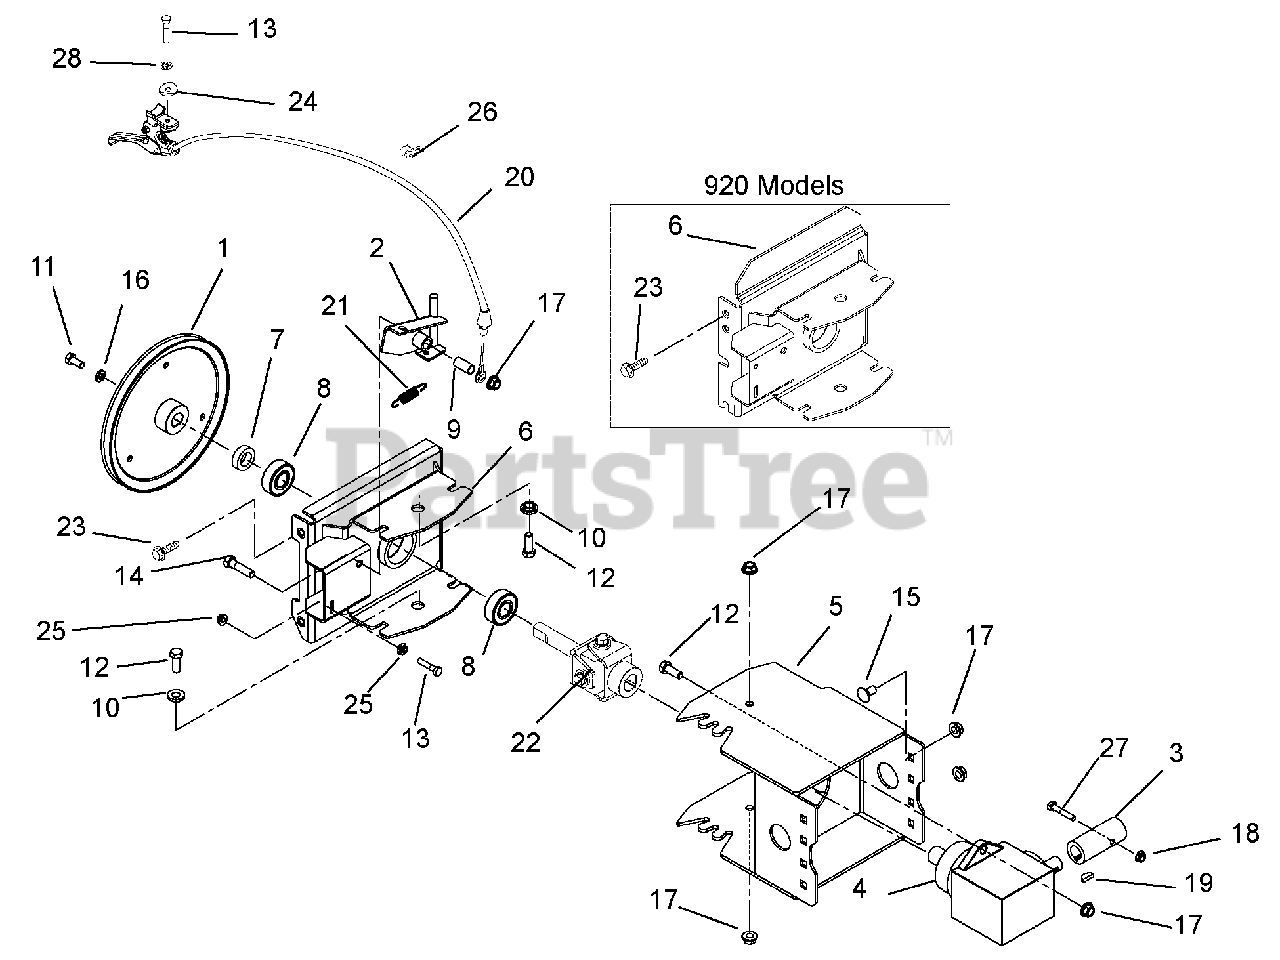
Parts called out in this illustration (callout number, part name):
1	PULLEY, 4L W/HUB, .75 X 8.5
2	ARM, PIVOT LOCK
3	HUB, COUPLING
4	GEAR BOX ASSEMBLY
5	ADAPTER WITH DECAL,BRUSH FRAME
6	ADAPTER, PLATE-32000 SERIES
6	ADAPTER, FRAME-20000 SERIES
7	SPACER .755X1.250X.370
8	BRG-BALL .750X1.781X.61
9	BSHG-SLV .385X.500X1.045
10	BSHG-FLG .406X.88X.270X.140
11	BLT-HEX .31-24X.75 YWZC GR5
12	@BLT-HEX .38-16X1.00 GR5 YWZC
13	@BLT-HEX .25-20X1.50 GR5 YWZC
14	@BLT-HEX .38-16X1.75 GR5 YWZC
15	@BLT-RDHDSQNK .38-16X.75 G5YZ
16	WSHR-LK .312X.097 HVY YWZC
17	@NUT-LK-TOP-FLG .38-16 YWZC
18	@NUT-LK-TOP-FLG .25-20 YWZC
19	KEY-WDRF .188X.75X.313 SAE 9
20	CABLE, REMOTE BRUSH LOCK
21	SG-TENS .06X.46X2.00
22	U-JOINT ASSY
23	@SCR-TAP .38-16X.75 HWH TR YWZ
23	@SCR-TAP .31-18X.75 HWH TR YWZ
24	SPACER, HANDLEBAR
25	@NUT-SPNLK-FLG .25-20 YWZC
26	J-CLAMP
27	@BLT-HEX .25-20X1.75 GR5 YWZC
28	WSHR-LK-INT .250 TH TYA
